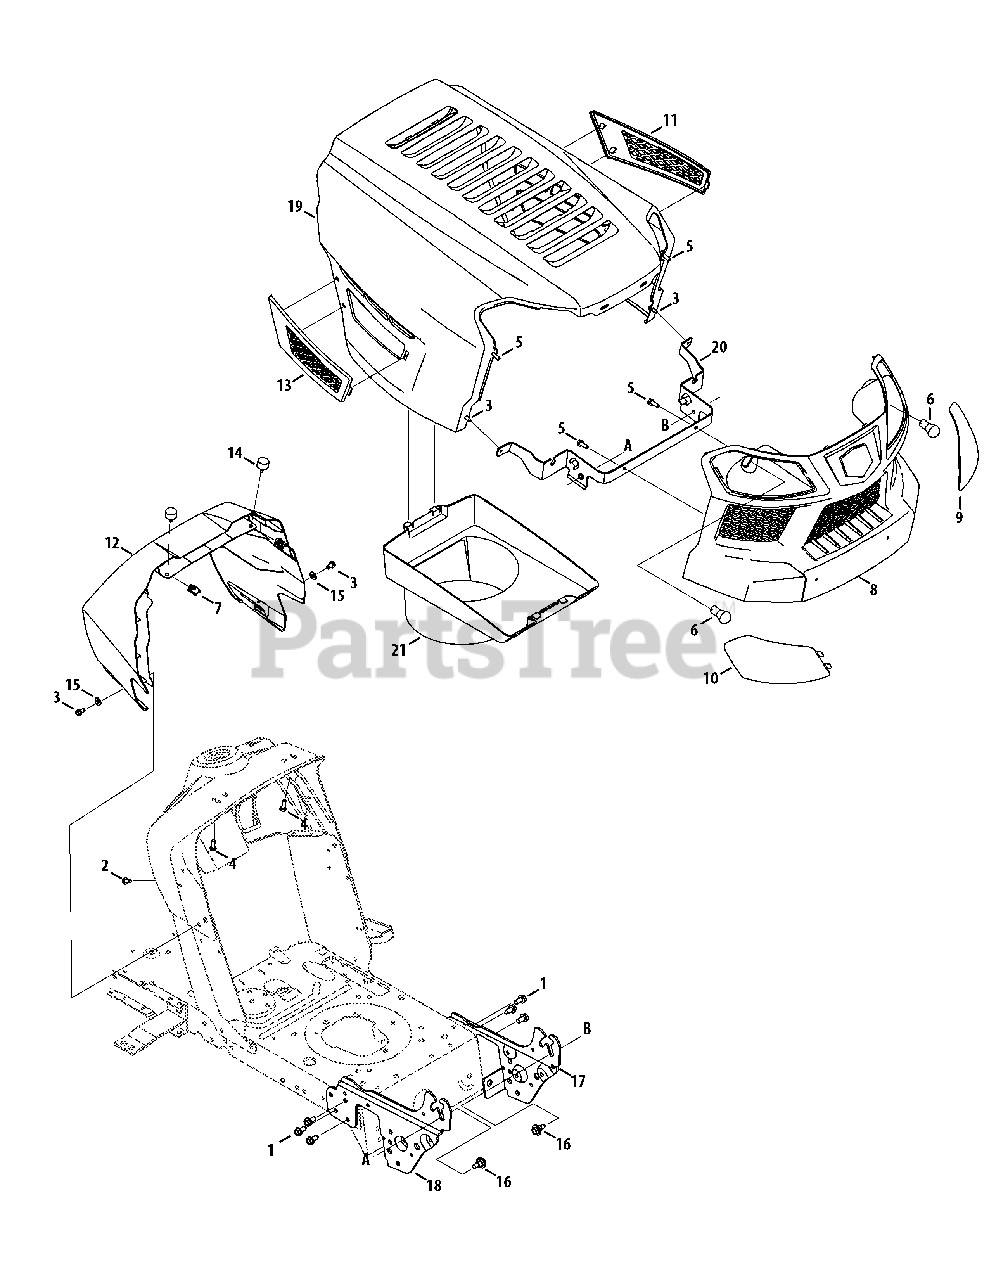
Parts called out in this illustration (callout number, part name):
1	Screw, 5/16-18 x .750
2	Self-Tap Screw, 1/4-20 x .5
3	Self-Tap Screw, 1/4-20 x .625
4	Self-Tap Screw, 1/4-20 x .75
5	Plastic Screw, 1/4-10 x .75
6	Headlight Bulb
7	U-Clip Nut
8	CPX Grill
9	Grill Lens, LH
10	Grill Lens, RH
11	Side Cover, LH
12	Dash Collar
13	Side Cover, RH
14	Bumper, .70 DIA X .53
15	Flat Washer, .25 X.630 X.0515
16	Shoulder Screw, .43 x .29, 5/16-18
17	Pivot Support Bracket, LH
18	Pivot Support Bracket, RH
19	Hood
20	Grill Pivot Bracket
21	Plenum
